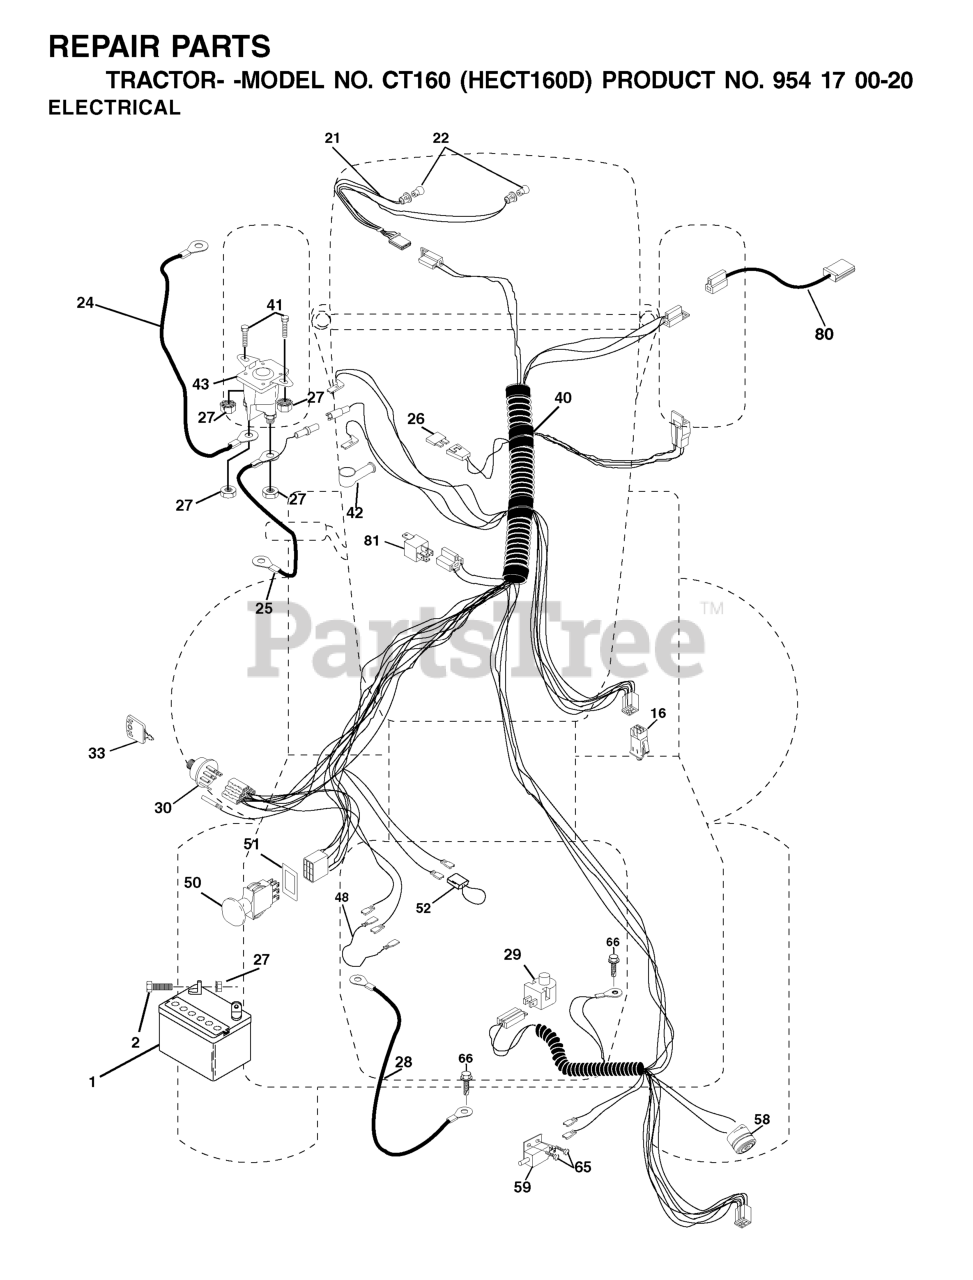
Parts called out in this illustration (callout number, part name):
1	BATTERY 12 VOLT 25 AMP
2	BOLT.HEX.1/4.X.3/4.DICHROMATE
16	SWITCH INTERLOCK
24	BATTERY CABLE GT
25	CABLE BATTERY
26	FUSE 20AMP
27	NUT
28	CABLE GROUND
29	PLUNGER SWITCH (COLOR:OLIVE)
30	IGNITION SWITCH
33	KEY MLD GEN DELTA
40	HARNESS.ING.CRD.ELECT
41	BOLT
42	TERMINAL COVER
43	REPL BY 532 1461-54
48	ADAPTER.AMMETER
50	RP.PTO.SWITCH.8 TERMINAL.BLACK
51	FRAME RETAINING RING
52	WIRE PROTECTION LOOP
58	BUZZER
65	Screw, Hex Wsh. Tap #10-16 x 1/2
66	SCREW LT
80	HARNESS, CLUTCH
81	RELAY.ASSY.T
